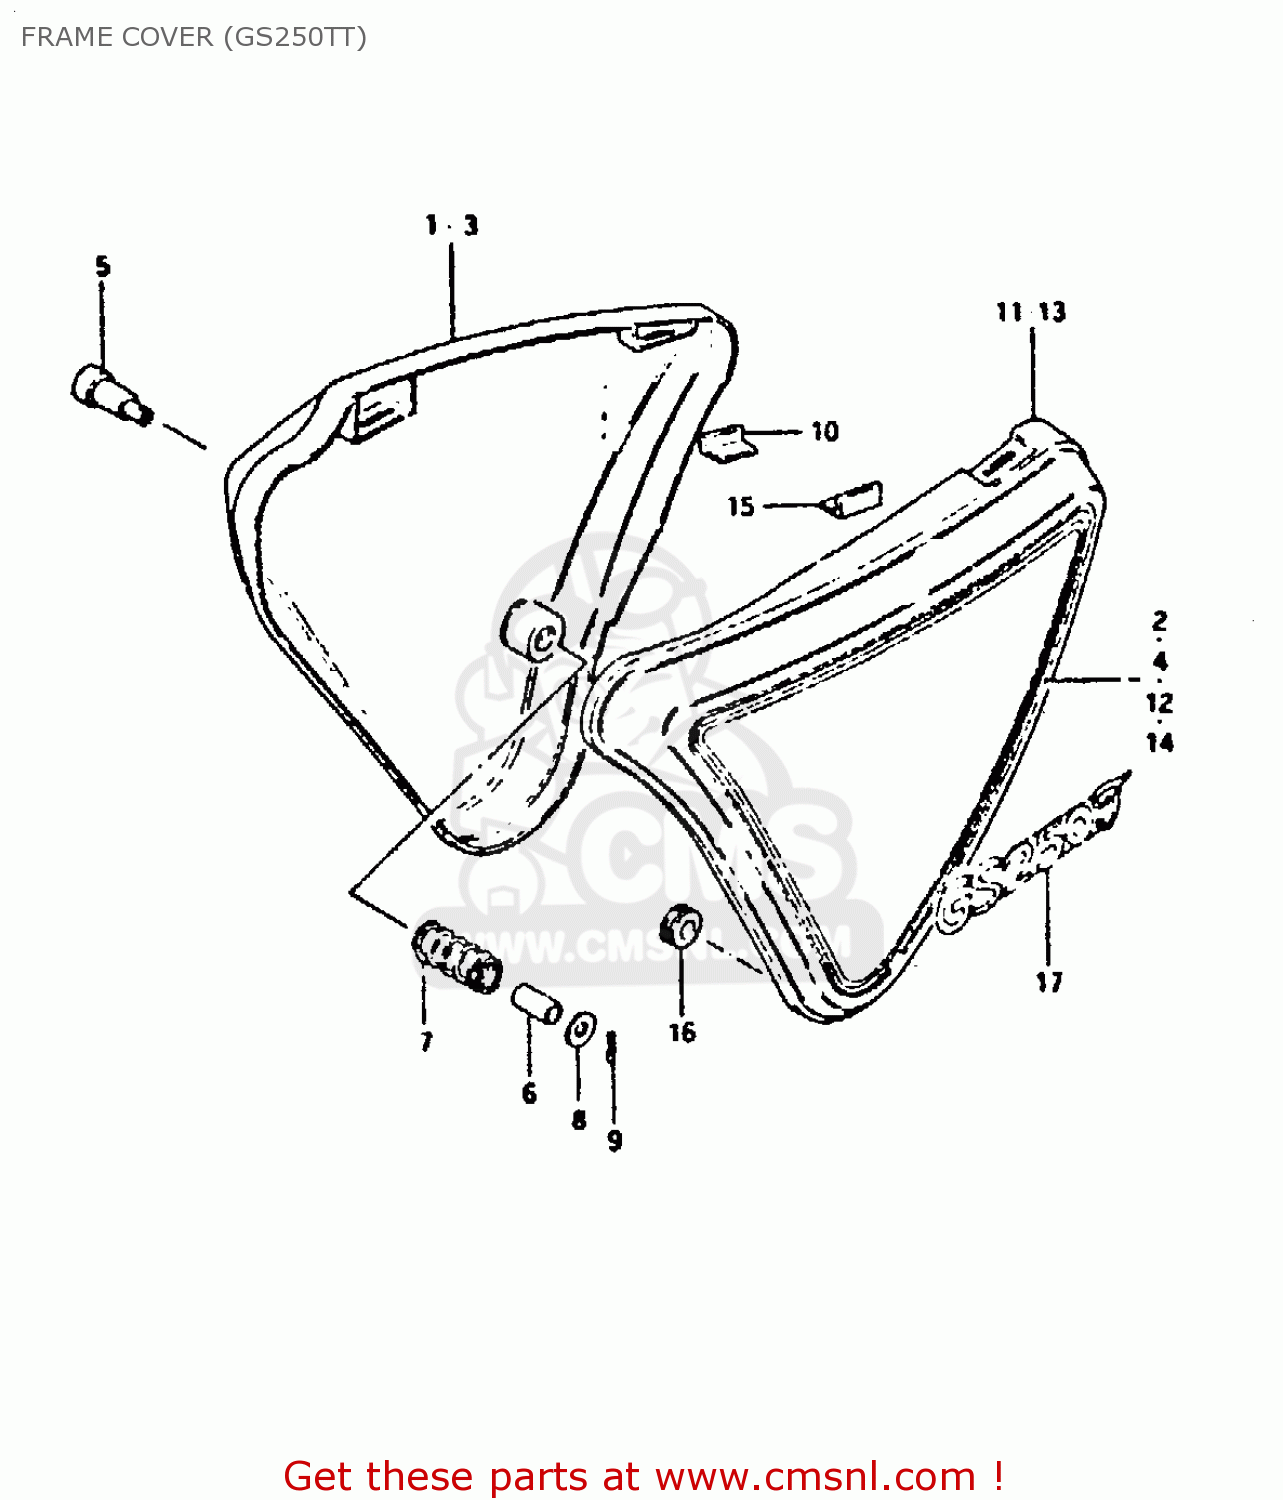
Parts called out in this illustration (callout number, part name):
1	COVER,FRAME,RIGHT
2	TAPE SET,FRAME COVER
3	COVER,FRAME,RIGHT
4	TAPE SET,FRAME COVER
5	KNOB,FRAME COVER,R
6	SPACER(14.9X17.3X13.5)
7	SPRING
8	WASHER (6.5X24X1.6)
9	PIN,SPRING(2.5X18)
10	CUSHION,FRAME COVER
11	COVER,FRAME,LEFT
12	TAPE SET,FRAME COVER
13	COVER,FRAME,LEFT
14	TAPE SET,FRAME COVER
15	CUSHION,FRAME COVER
16	CUSHION
17	EMBLEM,FRAME COVER
